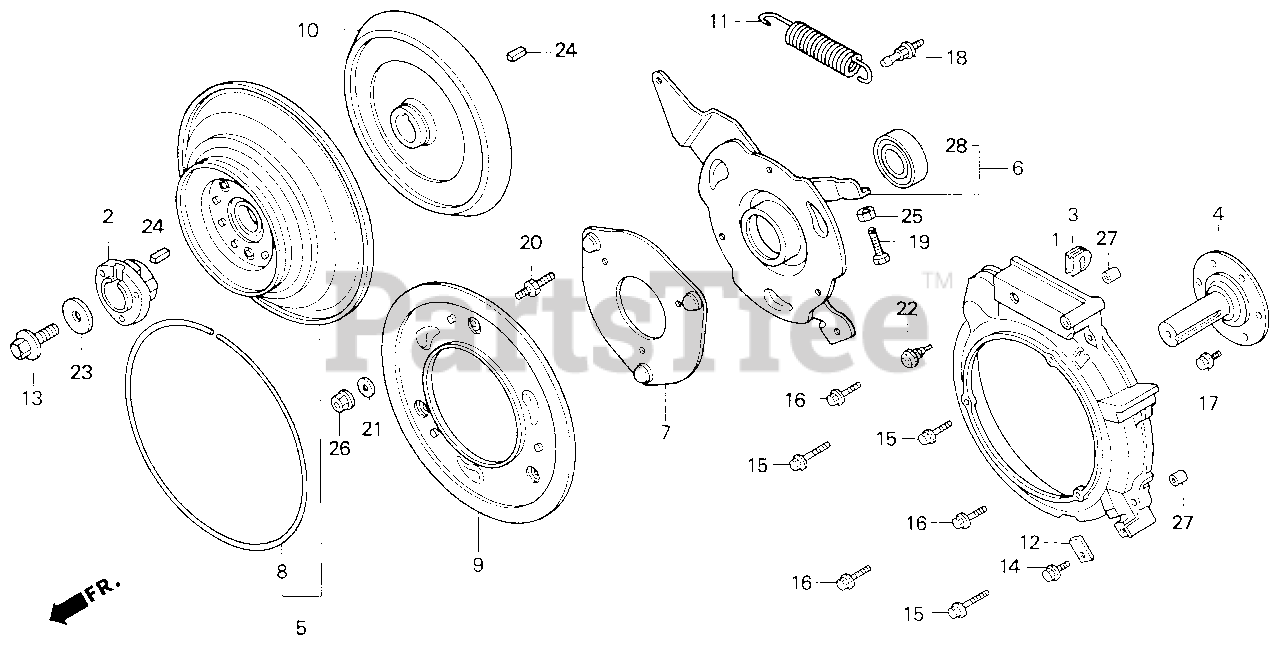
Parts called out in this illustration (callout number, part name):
1	COVER, FLYWHEEL
2	BOSS, COOLING FAN
3	GROMMET, WIRE
4	SHAFT, FR. P.T.O.
5	PULLEY ASSY., DRIVE
6	PLATE, BALL CONTROL
7	RETAINER, BALL
8	RING, P.T.O. CLUTCH
9	PLATE, BRAKE
10	PLATE, DRIVE
11	SPRING, RETURN
12	HOLDER, P.T.O. CABLE
13	BOLT, SPECIAL (10X25)
14	BOLT, FLANGE (6X12) (CT200)
15	BOLT, FLANGE (6X35)
16	BOLT, FLANGE (6X28)
17	BOLT, UBS (8X17)
18	BOLT, P.T.O. RETURN SPRING (6MM)
19	BOLT, ADJUSTING
20	BOLT, SPECIAL STUD (6MM)
21	WASHER (6MM)
23	WASHER (10X36X4.5)
24	KEY (7X7X18)
25	NUT, HEX. (8MM)
26	NUT, FLANGE (6MM)
27	PIN A, DOWEL (8X12)
28	BEARING, RADIAL BALL (6006UU)
